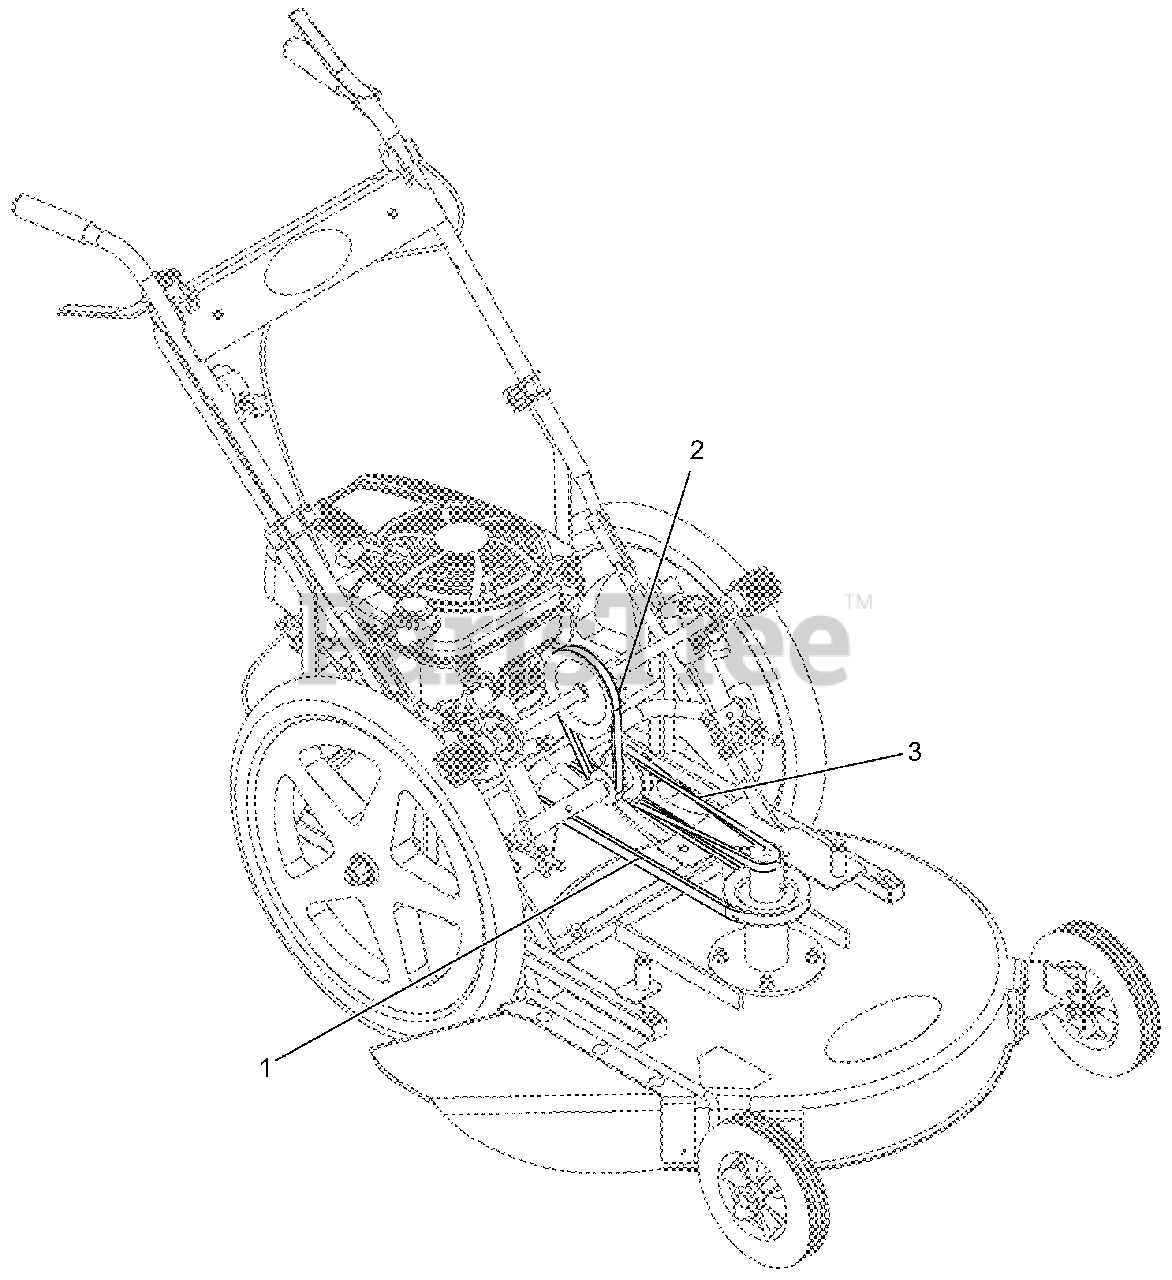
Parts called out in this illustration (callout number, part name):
1	V-BELT, HB-WRAPPED
2	V-BELT, 4L-RAW EDGE
3	V-BELT, 4L-RAW EDGE
